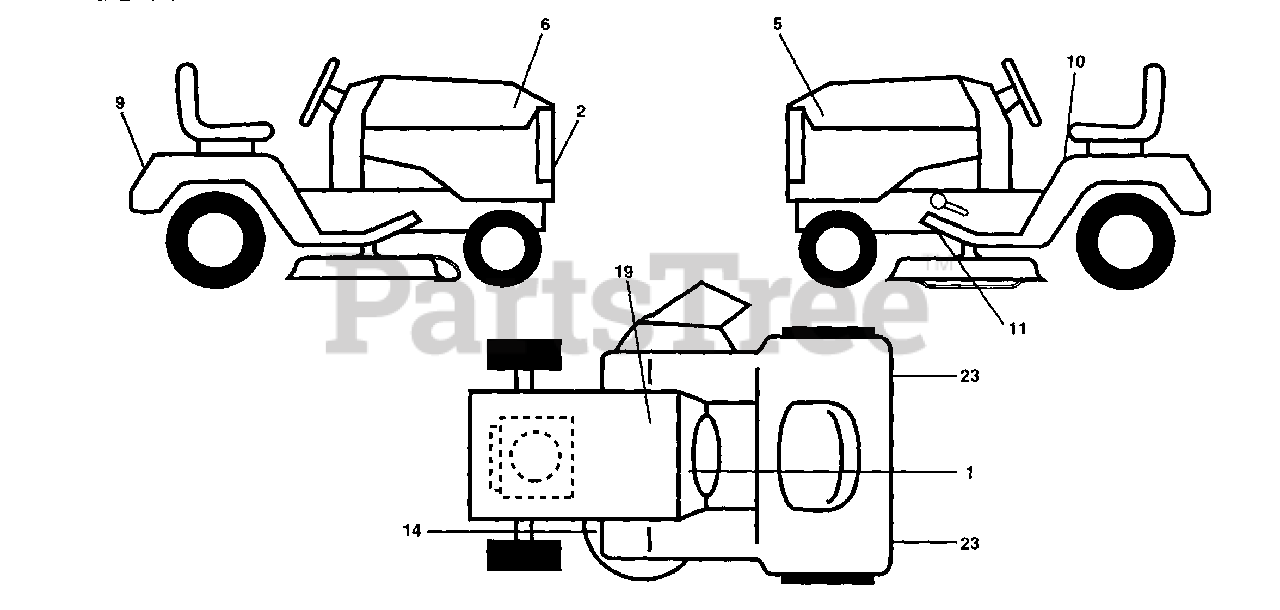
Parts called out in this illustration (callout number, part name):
1	Decal, Operating Instruction
2	Decal, Grille Husqvarna
5	Decal, Hood LH GT200
6	Decal, Hood RH GT200
9	Decal, Fender
10	Decal, Caution
11	Decal, Clutch/Brake
14	Decal, V-Belt Schematic
19	Decal, Battery
23	Reflector, Taillight
